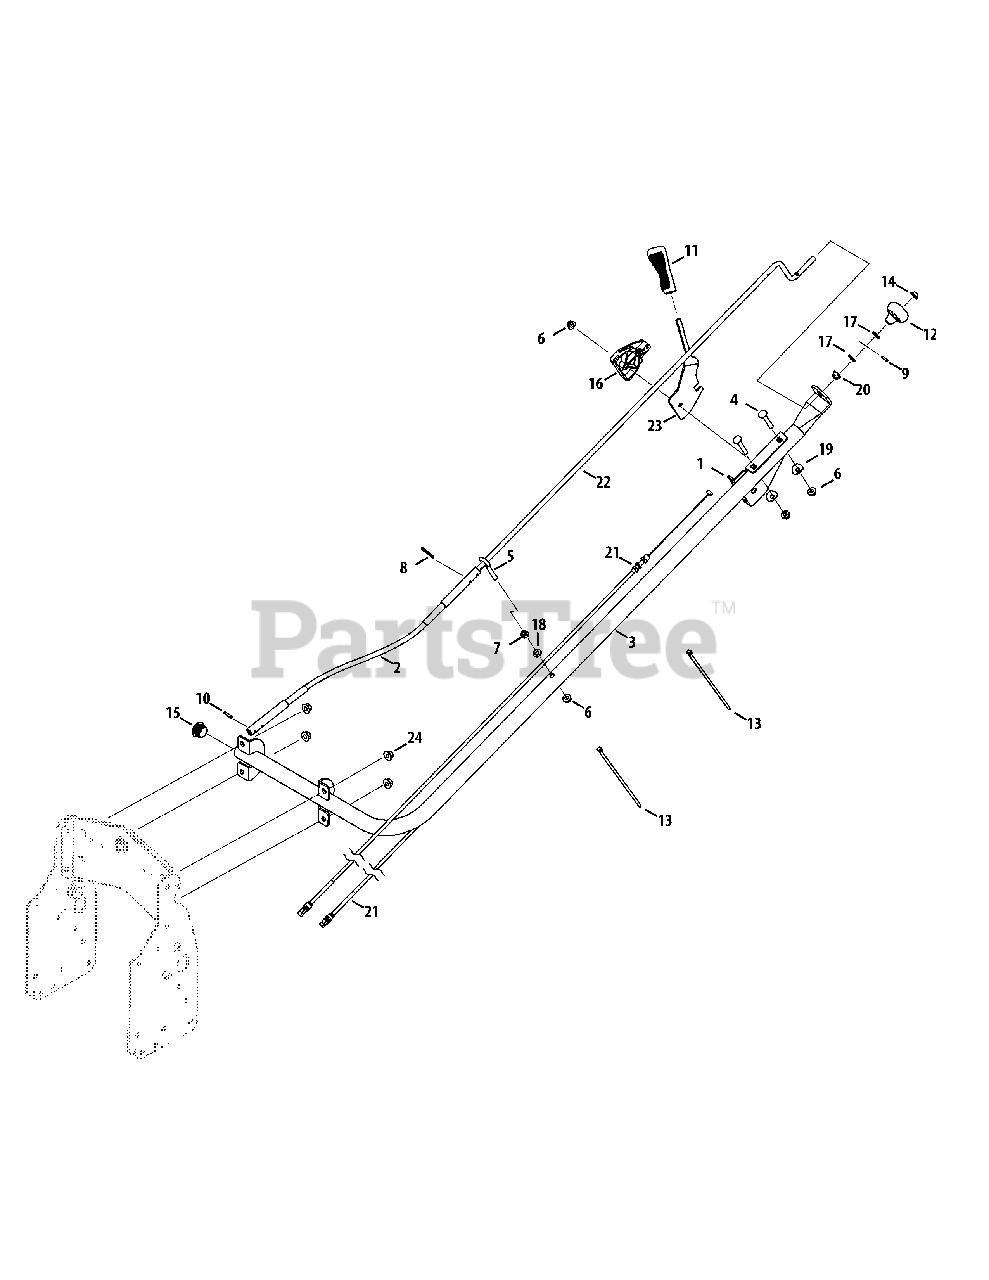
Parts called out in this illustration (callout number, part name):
1	Assembly, Chute Tilt Bracket
2	Control Assembly
3	Bracket Assembly
4	Screw, Carriage, 5/16-18, 2.00, Gr5
5	Bolt, Eye, 5/16-18 x 3.25
6	Nut, Flange Lock, 5/16-18, Grf, Nylon
7	Nut, Hex, 5/16-18, Gr5
8	Pin, Cotter, Int .08 x 1.42
9	Pin, Roll, 1/8 OD, .63
10	Pin, Spg, .156 Dia x .875 Lg
11	Grip, Handle, 3/8
12	Knob, .390 ID
13	Cable, Tie, 3/16 x .05 x 7.4
14	Cap, Push, 3/8 Rod
15	Plug, But, 1.250 Thin Wall
16	Guide, Cable, Chute Tilt
17	Washer, Flat, .375 x .738 x .063
18	Washer, Flat, .344 x .688 x .065
19	Washer, Saddle, .320 x .930 x .060
20	Bearing, Flange, Snap .385 ID
21	Cable, 74.5 Lg
22	Crank, Chute, .375 Dia x 34.63
23	Handle, Bracket, Chute Tilt
24	Nut, Flange Lock, 3/8-16, Grf, Nylon
